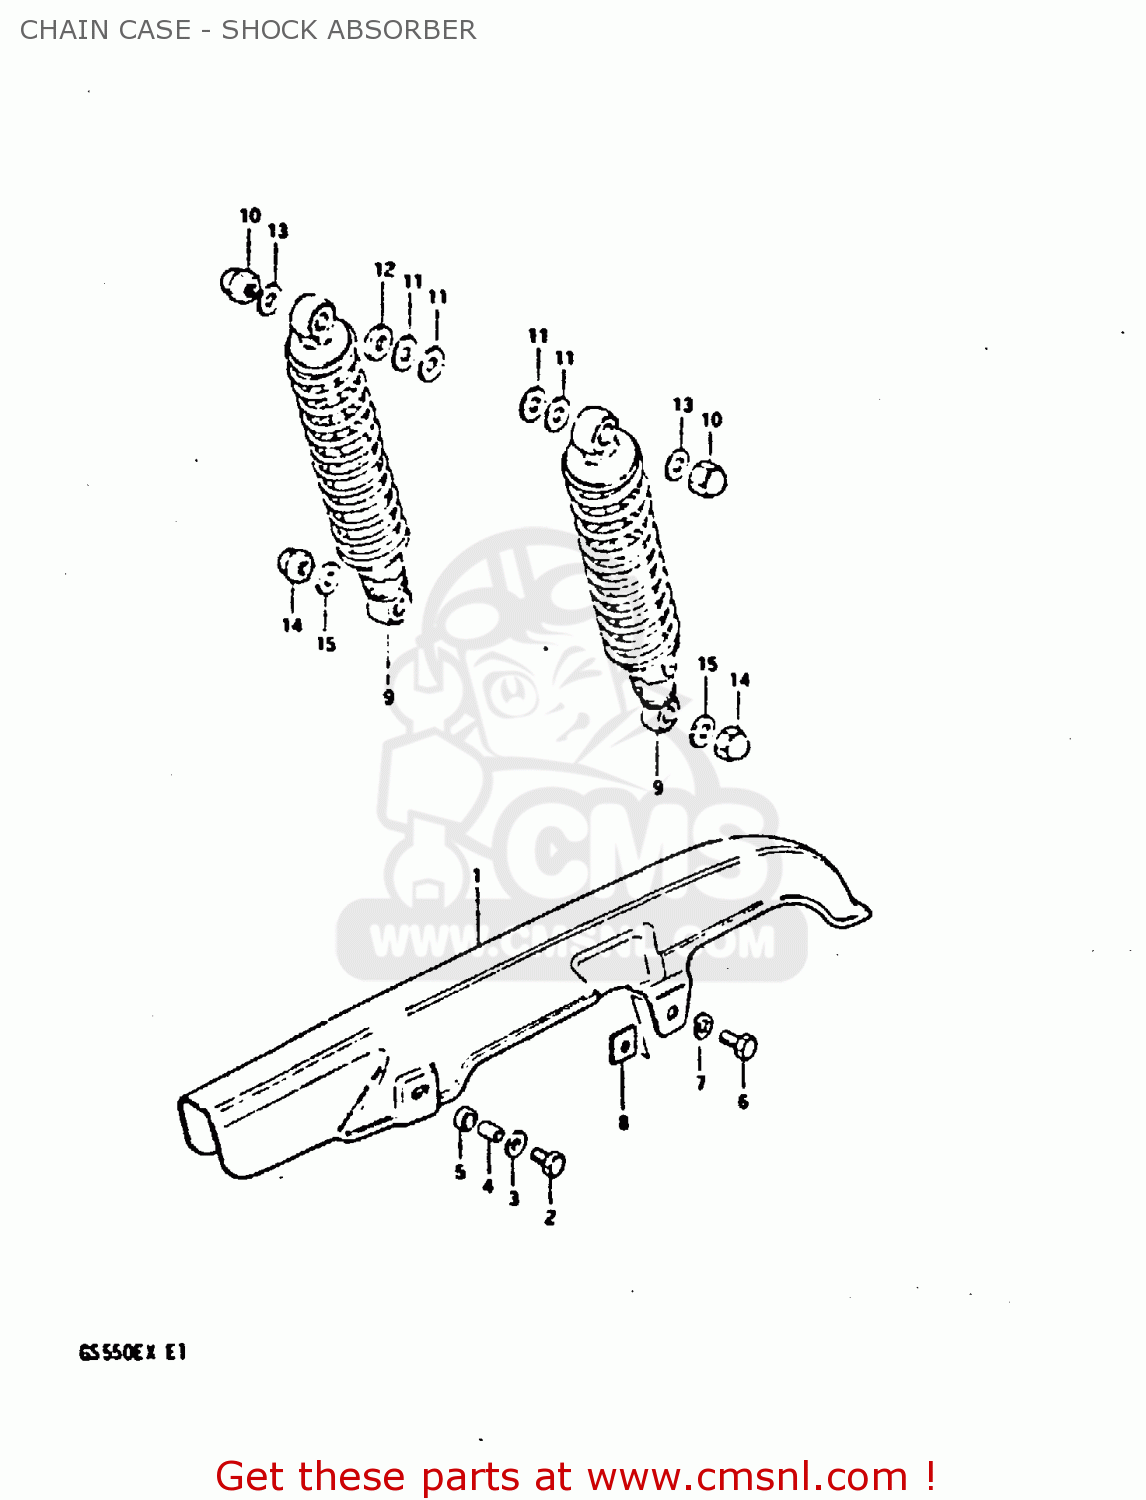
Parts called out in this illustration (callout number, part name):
1	CASE,CHAIN
2	BOLT
3	WASHER(6.5X18X1)
4	SPACER (6.1X8X5.2)
5	CUSHION
6	BOLT, UPPER
7	LOCK WASHER
8	NUT,CHAIN CASE RR
9	SHOCK ABSORBER, REAR
10	NUT
11	WASHER
12	WASHER (12.5X24X3.2)
13	WASHER
14	NUT, LOWER LH
15	WASHER
